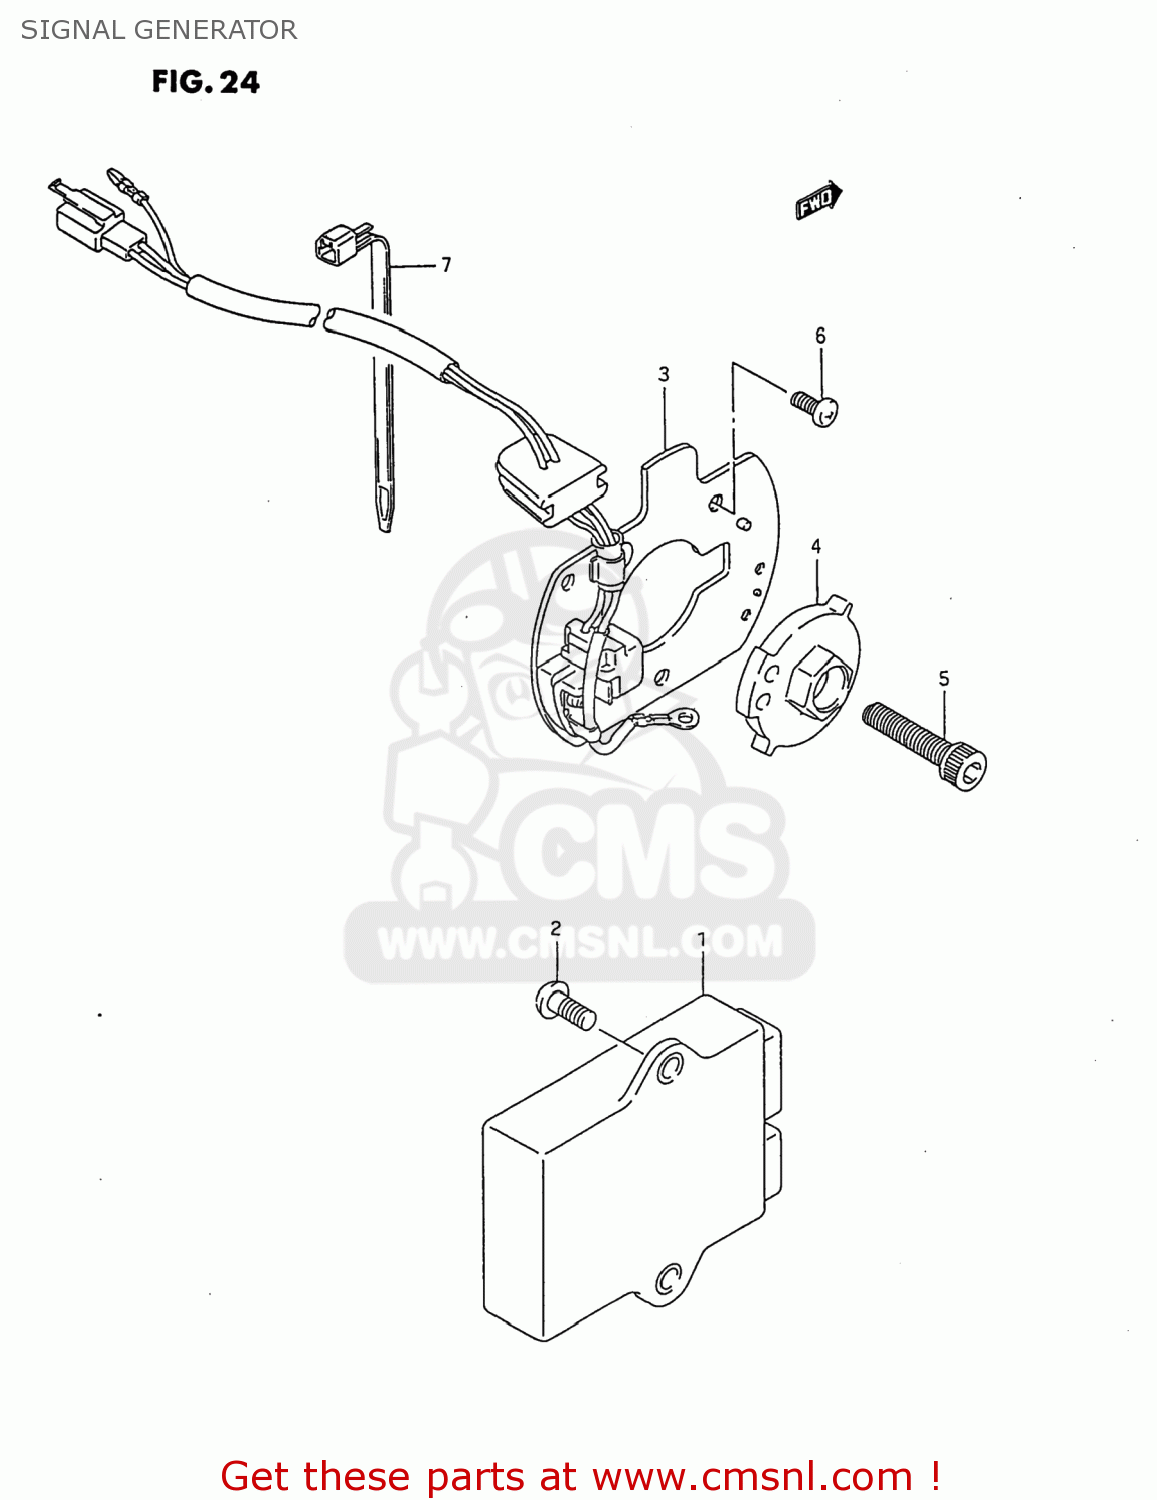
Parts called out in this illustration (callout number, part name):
1	IGNITER ASSEMBLY
2	SCREW 6X12
3	GENERATOR ASSY,SIGNAL
4	ROTOR,SIGNAL GENERATOR
5	BOLT
6	SCREW
7	CLAMP(L:95)
